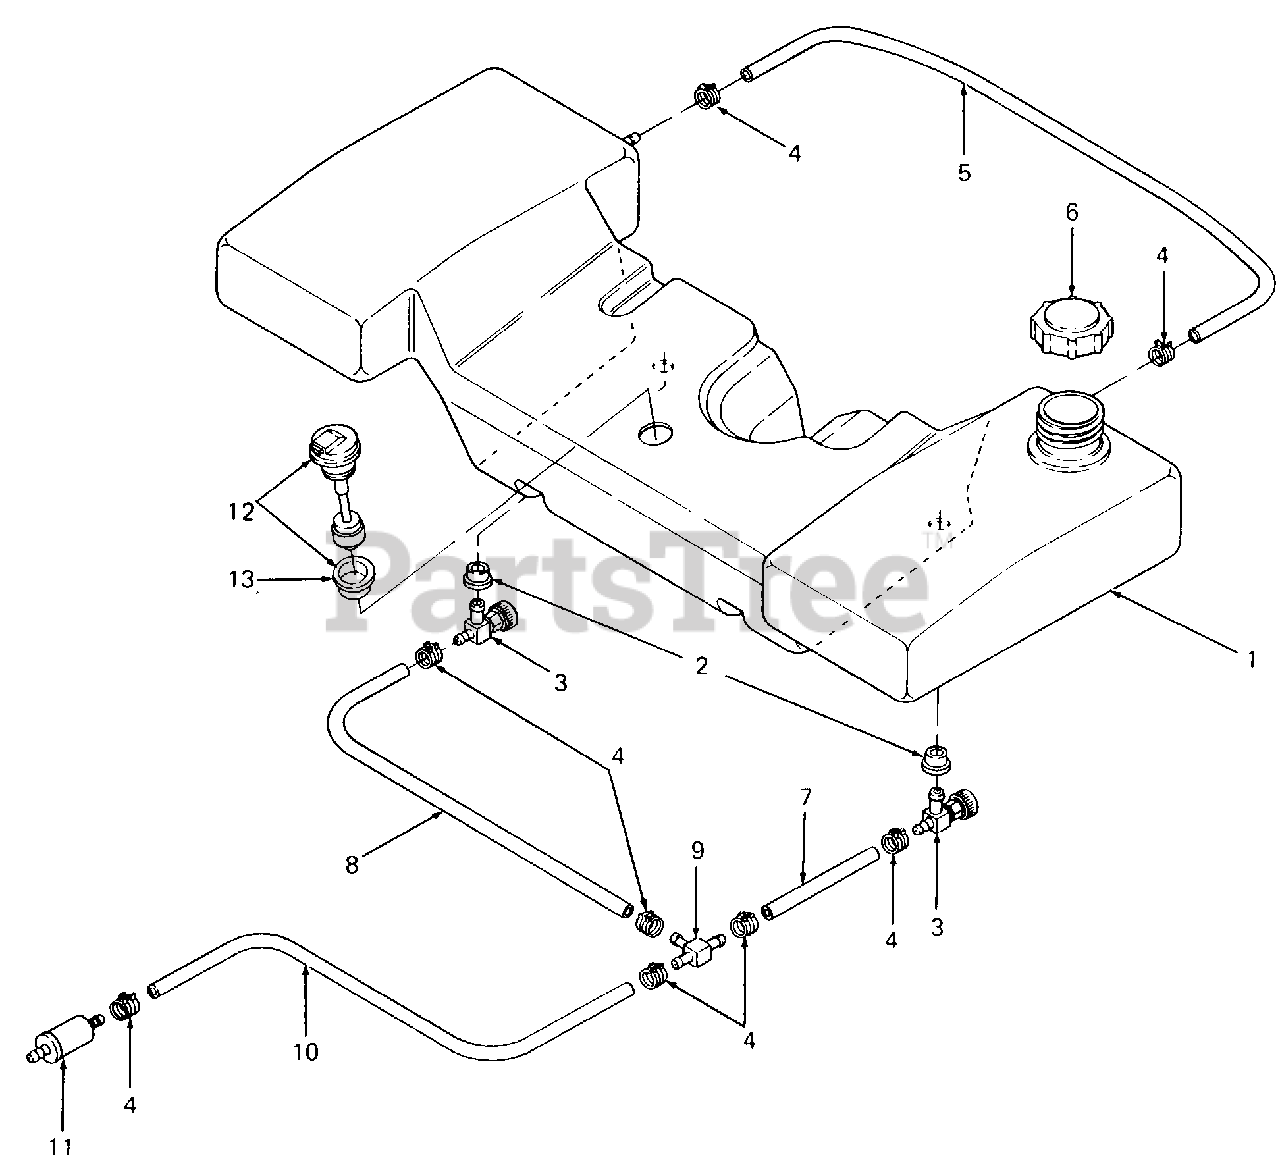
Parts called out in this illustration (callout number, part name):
1	Tank, Fuel
2	Bushing
3	Valve, Fuel Shutoff
4	Clamp, Hose
5	Line, Fuel -24" Lg
6	Cap, Fuel
7	Line, Fuel -5" Lg
8	Line, Fuel -17" Lg
9	T-Fitting
10	Line, Fuel -41" Lg
11	Filter, Fuel
12	Sensor, Low Fuel
13	Bushing, Rubber
